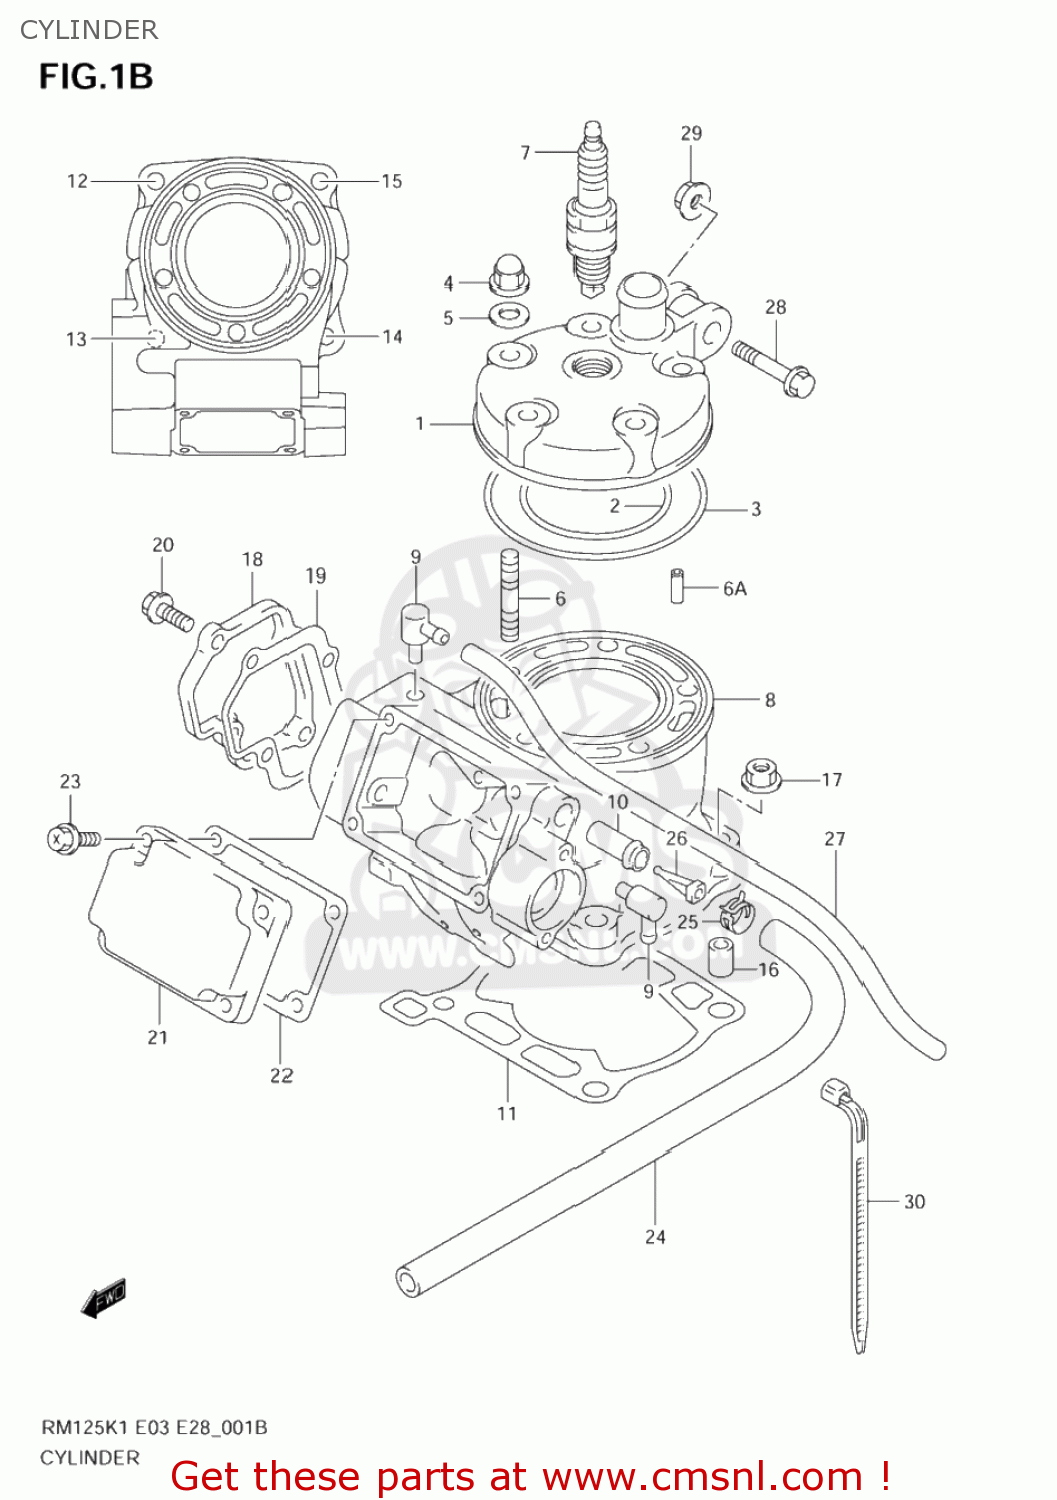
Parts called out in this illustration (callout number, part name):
1	HEAD,CYLINDER
2	O RING,CYLINDER HEAD NO.1
3	O RING,CYLINDER HEAD NO.2
4	NUT
5	GASKET(8.5X17X2.3) (NAS)
6	BOLT,STUD
6A	PIN
7	PLUG,SPARK(R6918B-8)
8	CYLINDER SET
9	UNION,BREATHER HOSE
10	UNION
11	GASKET,CYLINDER (NAS)
12	BOLT,STUD
13	BOLT,STUD
14	STUD BOLT
15	BOLT,STUD
16	PIN(8.4X11X14)
17	NUT
18	COVER,CYLINDER NO.1
19	GASKET,CYLINDER COVER NO.1 (NAS)
20	BOLT
21	COVER,CYLINDER NO.2
22	GASKET,CYL COVER NO.2
23	BOLT
24	HOSE
25	CLIP
26	FILTER,EXH VALVE BREATHER HOSE
27	HOSE(5X8.2X600)
28	BOLT(10X47.5)
29	NUT
30	CLAMP(L:165)
